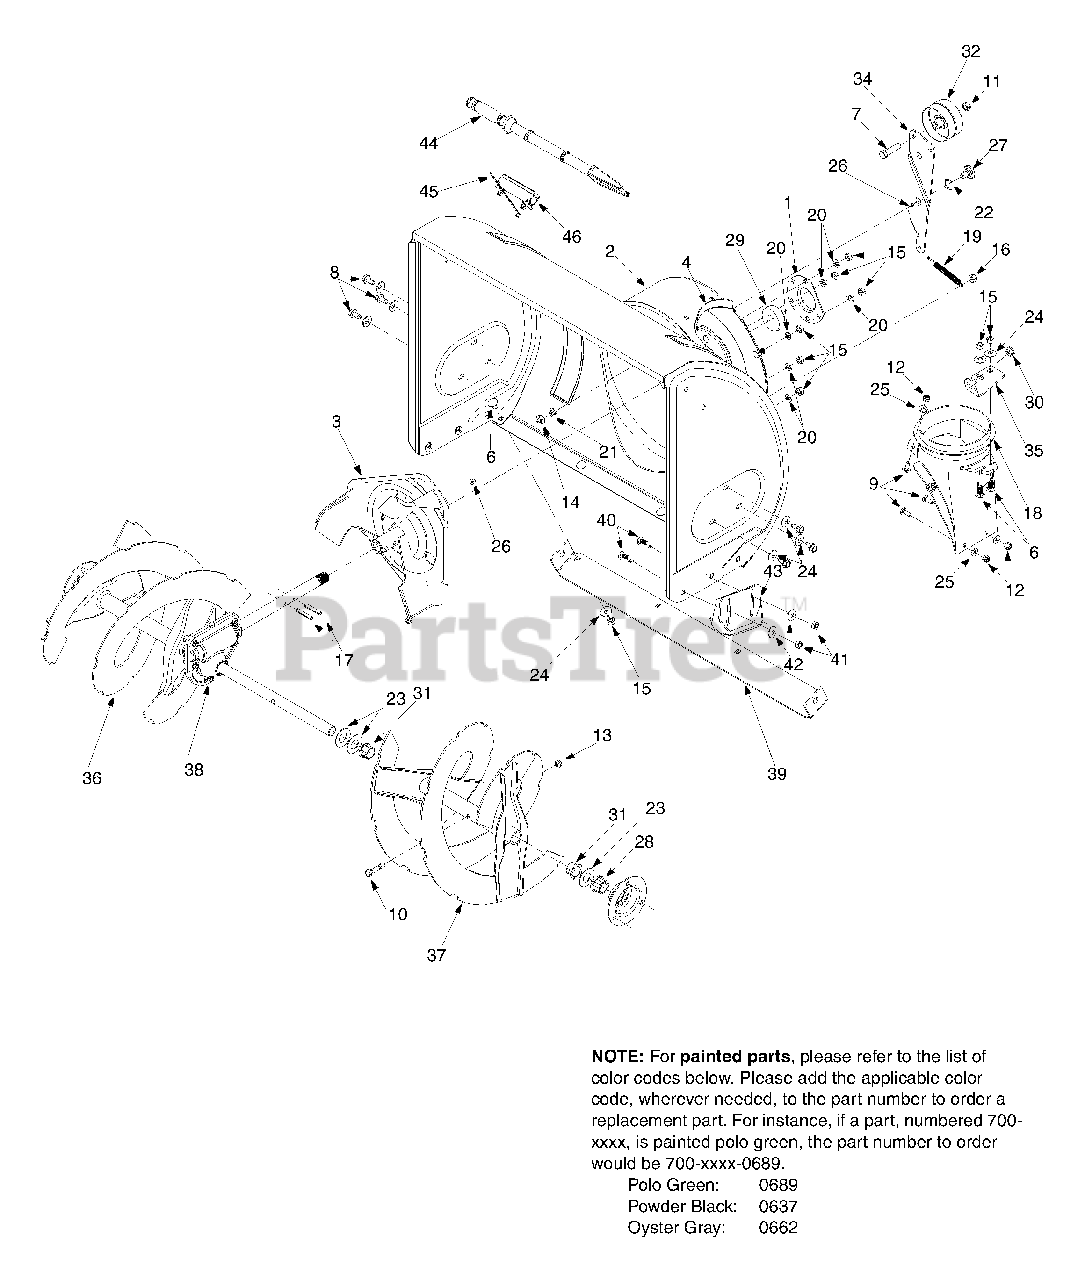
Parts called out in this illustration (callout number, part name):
1	Bearing Housing
6	Carriage Bolt 5/16-18 x .75" Gr.2
7	Hex Screw 3/8-24 x 1.5" Gr.5
8	Hex Washer Head Self-Tapping Screw 5/16-18 x .62"
9	Carriage Screw 1/4-20 x .75"
10	Shear Bolt 5/16-18 x 1.5"
11	Jam Nut 3/8-24
12	Hex Lock Nut 1/4-20
13	Hex Lock Nut 5/16-18
14	Hex Nut 3/8-16 Gr.2
15	Hex Nut 5/16-18 Gr.5
16	Hex Patch Nut 5/16-18
17	Spiral Pin
18	Chute Adapter
19	Extension Spring
20	Lock Washer
21	Lock Washer
22	Flat Washer
23	Flat Washer
24	Belleville Washer
25	Flat Washer
26	Grease
27	Shoulder Screw
28	Hex Flange Bearing
29	Flange Ball Bearing
30	Bushing
31	Flange Bushing
32	Flat Idler
38	Gear Assembly: Auger 24"
40	Carr. Bolt: 5/16-18 x 0.75
41	Hex Nut: 5/16-18 Gr.5
42	Belleville Washer
44	Chute Clean-Out Tool
45	Cable Tie
46	Clean-Out Tool Mount
